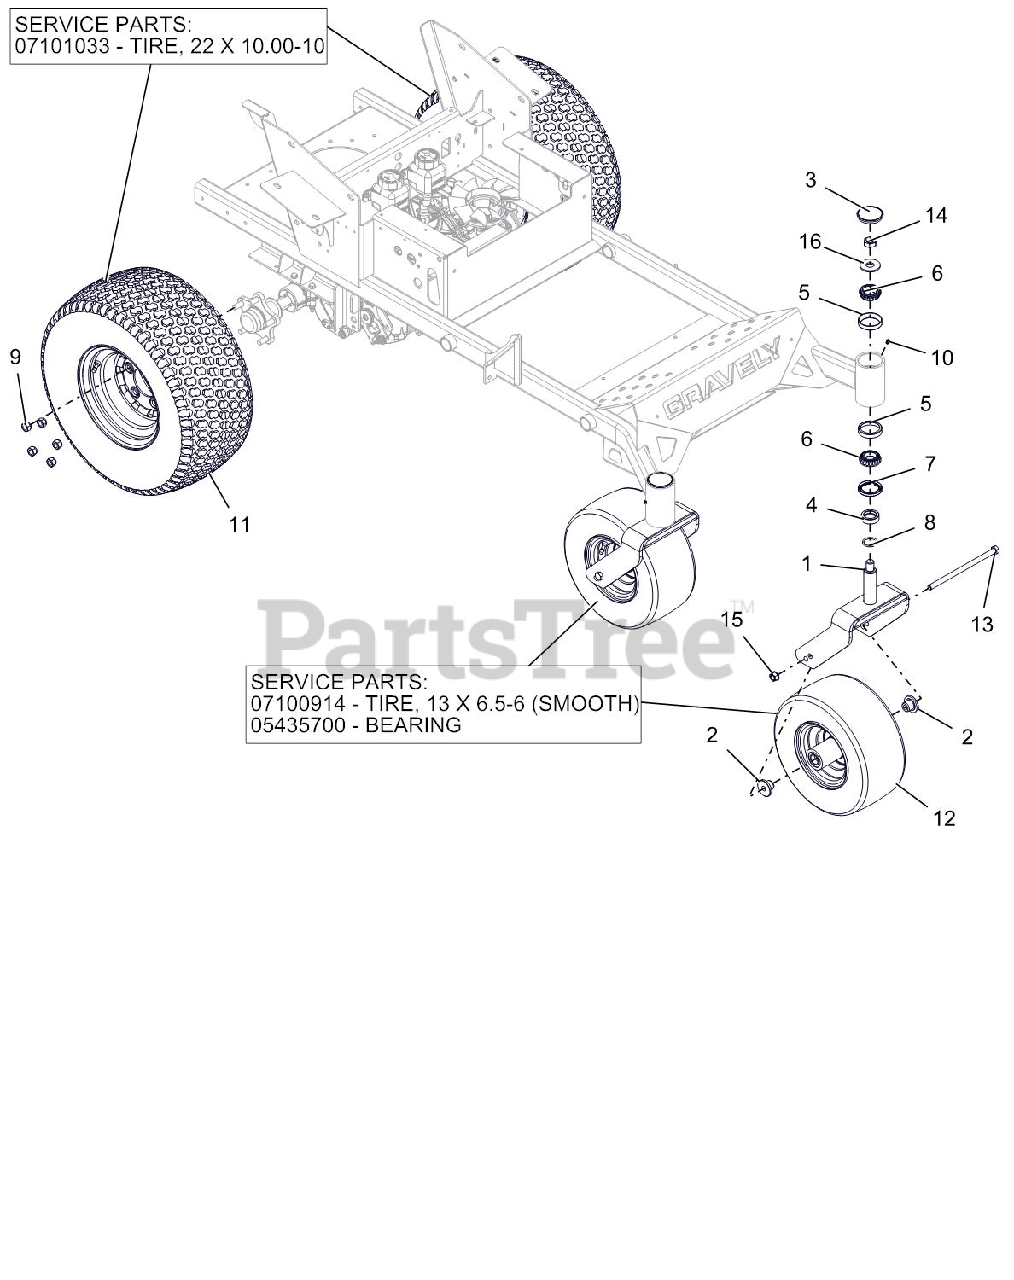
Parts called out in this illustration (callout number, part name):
1	CASTER FORK WMT - RED
2	SPACER, FRONT WHEEL
3	CAP, DUST
4	SPCR, FRONT CASTER FORK
5	BRG-CUP 2.328X.465
6	BRG-CONE 1.25X.66
7	SEAL, OIL 1.75 X 2.332 X .312
9	WHEEL NUT .500-20 YZ
10	FTG, .25-28 FLUSH MNT GREASE
11	TIRE, 22 X 10.00-10
11	ASM, WHL/TIRE 22X10.00-10
12	BRG, 25MM ID X 52MM OD X 15MM
12	TIRE, 13X6.50-6 SMOOTH
12	ASM, WHL/TIRE 13X6.50-6
13	@BLT-HEX .50-13X9.00 GR5 YWZC
14	NUT-JAM TOPLK .75-16 YWZC
15	@NUT-LK-TOP-FLG .50-13 YWZC
16	@WSHR-FL-STL.812X2.00X.148YWZC
